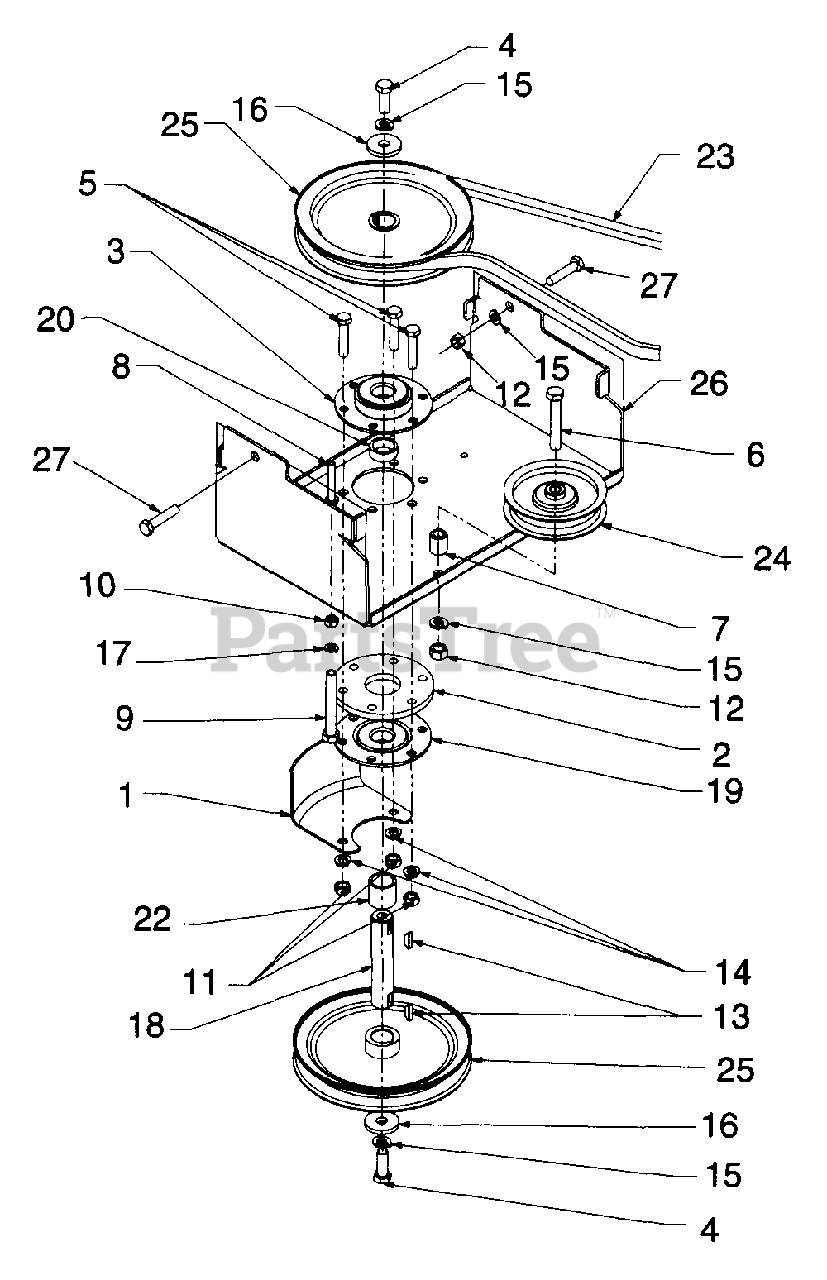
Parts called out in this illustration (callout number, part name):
1	Belt Guard
2	Plt:Spdl:Spcr.
3	Open Brg. Housing 1.85
4	HHCS:3/8-24:1.00:Gr.5:Lock
5	HHCS:5/16-24:1.50:Gr.5:Std.
6	HHCS:3/8-16:2.25:Gr.5:Std.
7	Spcr:.385 x .623 x .750 Lg.
8	Pin:Gde:.250 Dia. x 1.68 Lg.
9	Pin:Clevis:.375 Dia. x 2.63 Lg.
10	Nut:Lock:1/4-20
11	Hx. Nut:5/16-24:Gr.A:
12	Hx. Nut:3/8-16:Gr. A
13	Key:Hi-Pro 3/16 X 5/8
14	Wash:Lock: 5/16:Regular Duty
15	Wash:Lock:3/8:Regular Duty
16	Flat Washer .406 I.D. x 1 1/4 O.D.
17	Wash:Lock:1/4:Regular Duty
18	Shaft- .787 Dia. x 3.81 Lg.
19	Hsg. Asm.:Bearing
20	Spacer .790 I.D. x.347 Lg.
22	Spacer .80 I.D. x 1.00 O.D. x .900
23	Belt: V: 1/2 x 52.00 Lg.
24	Fl-Idler w/ Flanges 3.75 O.D.
25	Pulley:V Typ:6.50 O.D.
26	Brkt: Carriage
27	HHCS. 3/8-16:1.00 Gr.5
